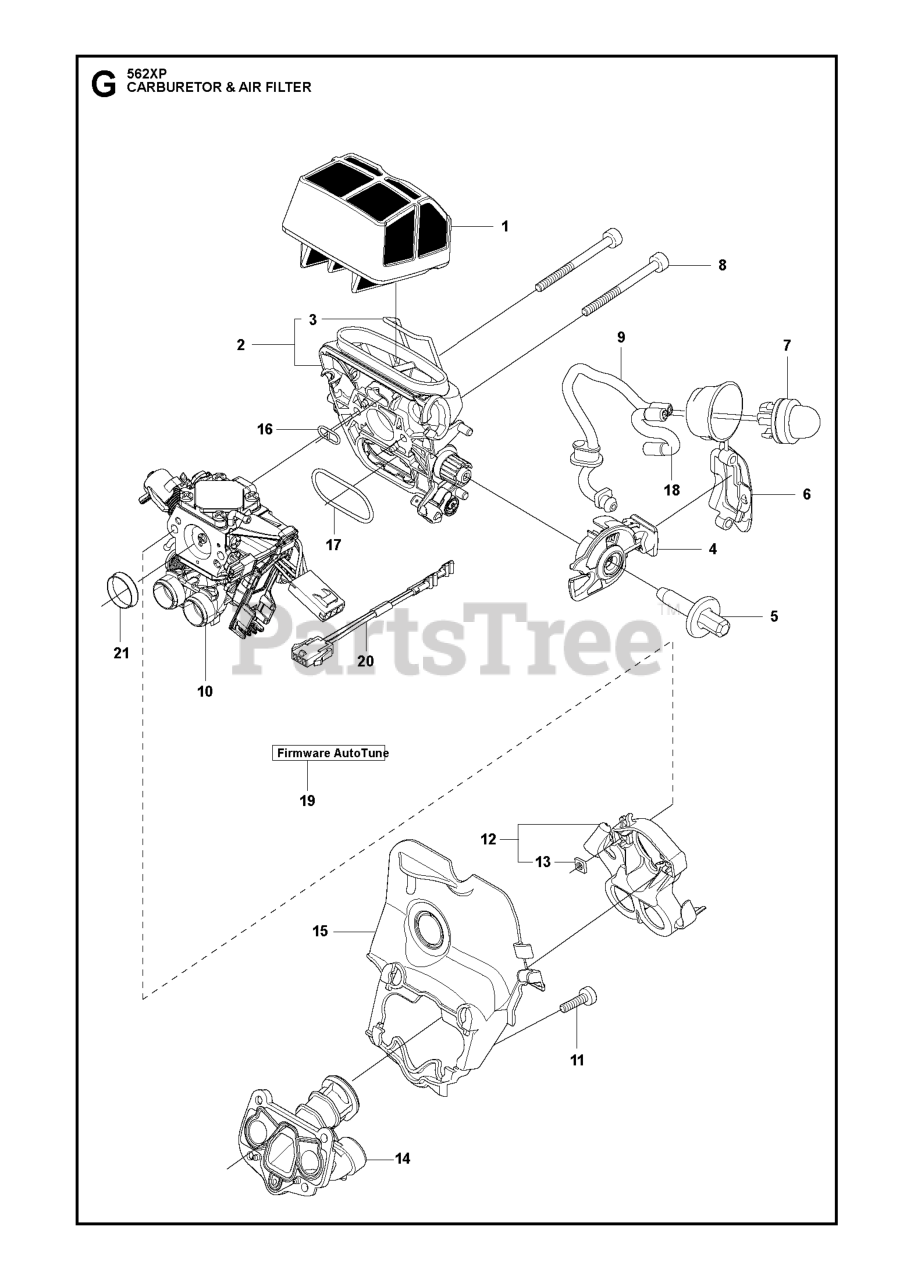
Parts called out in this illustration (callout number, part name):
1	AIR FILTER ASSY BLCK 80 MICRON
1	AIR FILTER ASSY YLLW 44 MICRON
1	AIR FILTER ASSY NATURAL FELT
1	AIR FILTER ASSY
2	FILTER HOLDER ASSY
4	CHOKE CONTROL ASSY CHOKE/STOP
7	AIR PURGE BUBBLE
8	SCREW ITXSCM
9	FUEL HOSE
9	VENTILATING HOSE,KIT
10	CARBURETTOR KIT 60CC
10	CARBURETOR KIT 555 AUTOTUNE
11	SCREW ITXSCM M4X15 T27 12.9 T
12	FLANGE CARBURETTOR FLANGE
14	INLET PIPE
14	INLET PIPE COLD RESISTANT
15	INTERMEDIATE WALL
20	WIRING ASSY
21	SUPPORT SLEEVE
